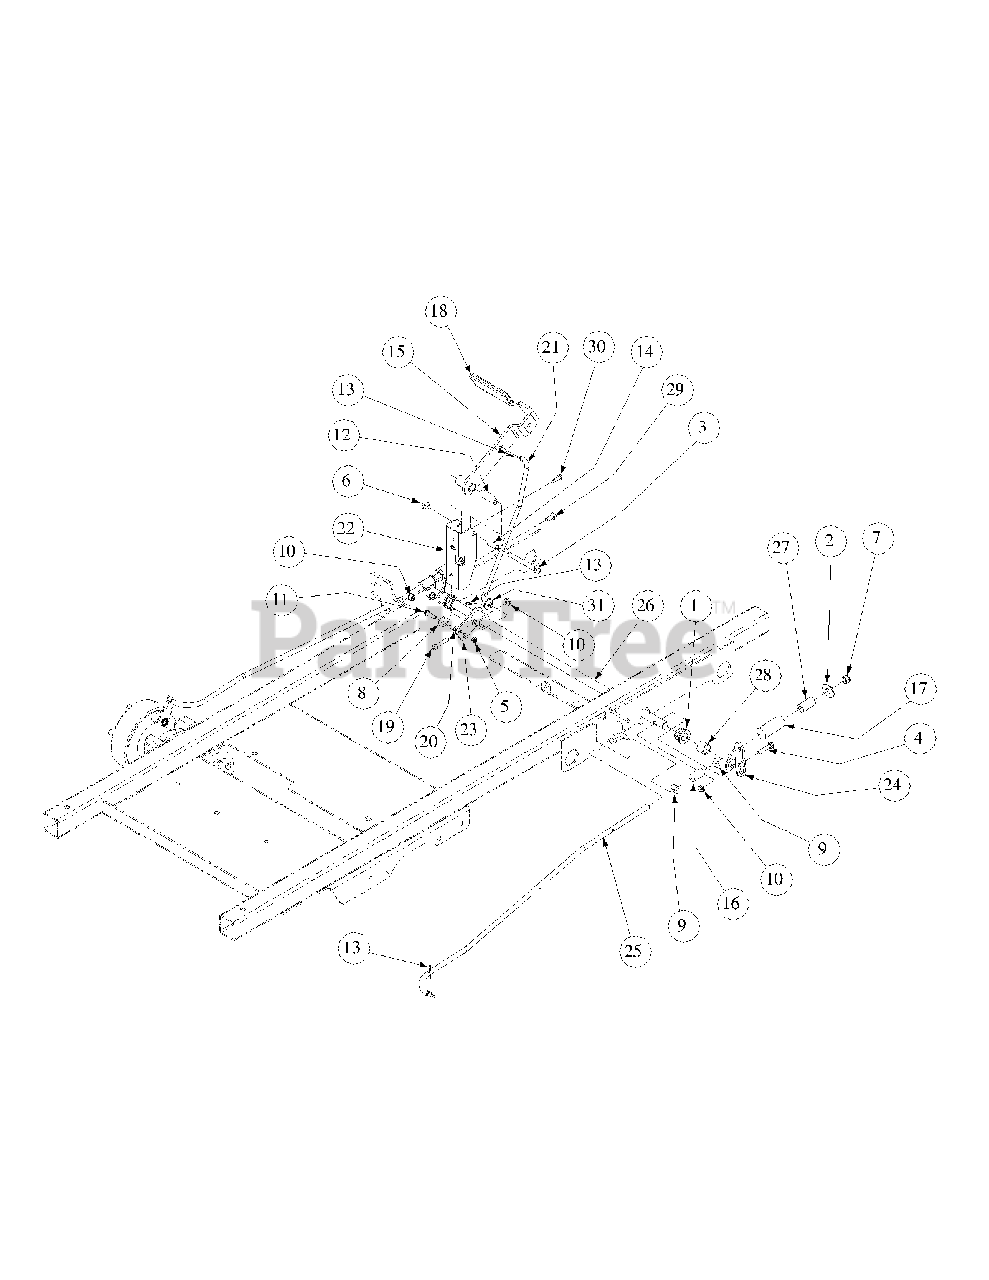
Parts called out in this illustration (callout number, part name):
1	Hex Flange Bearing, .752 ID
2	Flat Washer, 1/2
3	Hex Cap Screw, 3/8-16 x 3-1/4
4	Hex Cap Screw, 5/16-18 x 1-1/2
5	Lock Nut, 1/4-20, Nylon Insert
6	Flange Lock Hex Nut, 3/8-16
7	Nylock Nut, 7/16-14
8	Spacer, Control Rod
9	Washer, .469 ID x .875 OD x .105
10	Hex Flange Lock Nut, 5/16-18
11	Self Tapping Screw, 1/4-20 x 1.00
12	Spacer, .39 x .63 x 1.75
13	Cotter Pin, .072 x 1.12 Lg
14	Spacer, .375 x .50 x .75 Lg
15	Brake Handle
16	Neutral Brake Spring
17	Force Brake Spring
18	Parking Brake Grip
19	Socket Head Cap Screw, 5/16-18 x 1.50
20	Spacer, .375 OD x .257 ID x .438
21	Brake Rod
22	Parking Brake Mounting Bracket
23	Brake Arm Assembly
24	Brake Bracket
25	Linkage Brake Rod
26	Pivot Brake Shaft
27	Low Pressure Hose
28	Spacer, .76 ID x 1.0 OD x .75
29	HHCS, 5/16-18 x 1.0
30	Screw, TT, 1/4-20, 0.75, Hex Index Washer
31	Flat Washer, .406 ID, 1.0 OD, .105
